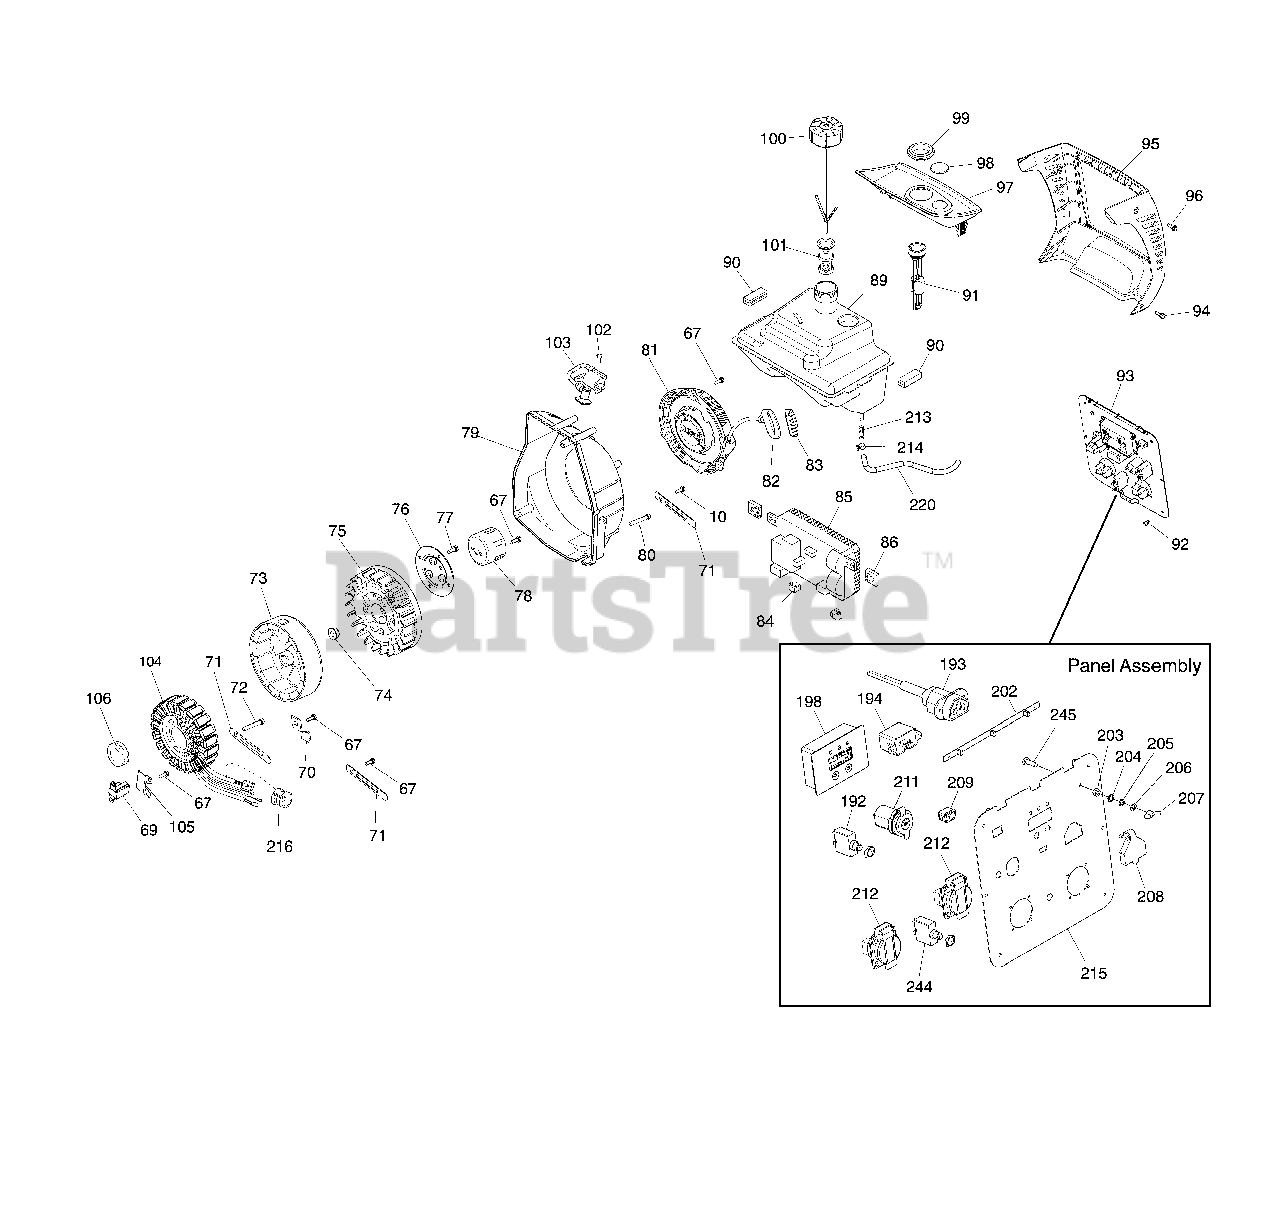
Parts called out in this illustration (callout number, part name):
10	SCREW
67	BOLT, M6 X 12
69	TRIGGER-IGNITION
70	BRACKET
71	BRACKET
72	SCREW, M6 X 60
74	NUT, FLANGE M14
76	TERMINAL
77	BOLT, M6 X 16
79	COVER-FAN
80	BOLT, M6 X 55
81	STARTER-REWIND
82	GRIP
84	MOUNT-VIBRATION
86	MOUNT-VIBRATION
90	MOUNT-VIBRATION
92	SCREW
93	PANEL-CONTROL
94	SCREW, M5 X 30
96	SCREW, M6 X 56
101	FILTER-FILLER NECK
102	SCREW
103	COIL-IGNITION
105	BRACKET
106	SEAL-OIL
192	BREAKER-CIRCUIT
193	PORT-PARALLEL
214	CLAMP
215	PANEL-CONTROL
216	COVER-RUBBER
244	BREAKER-CIRCUIT
